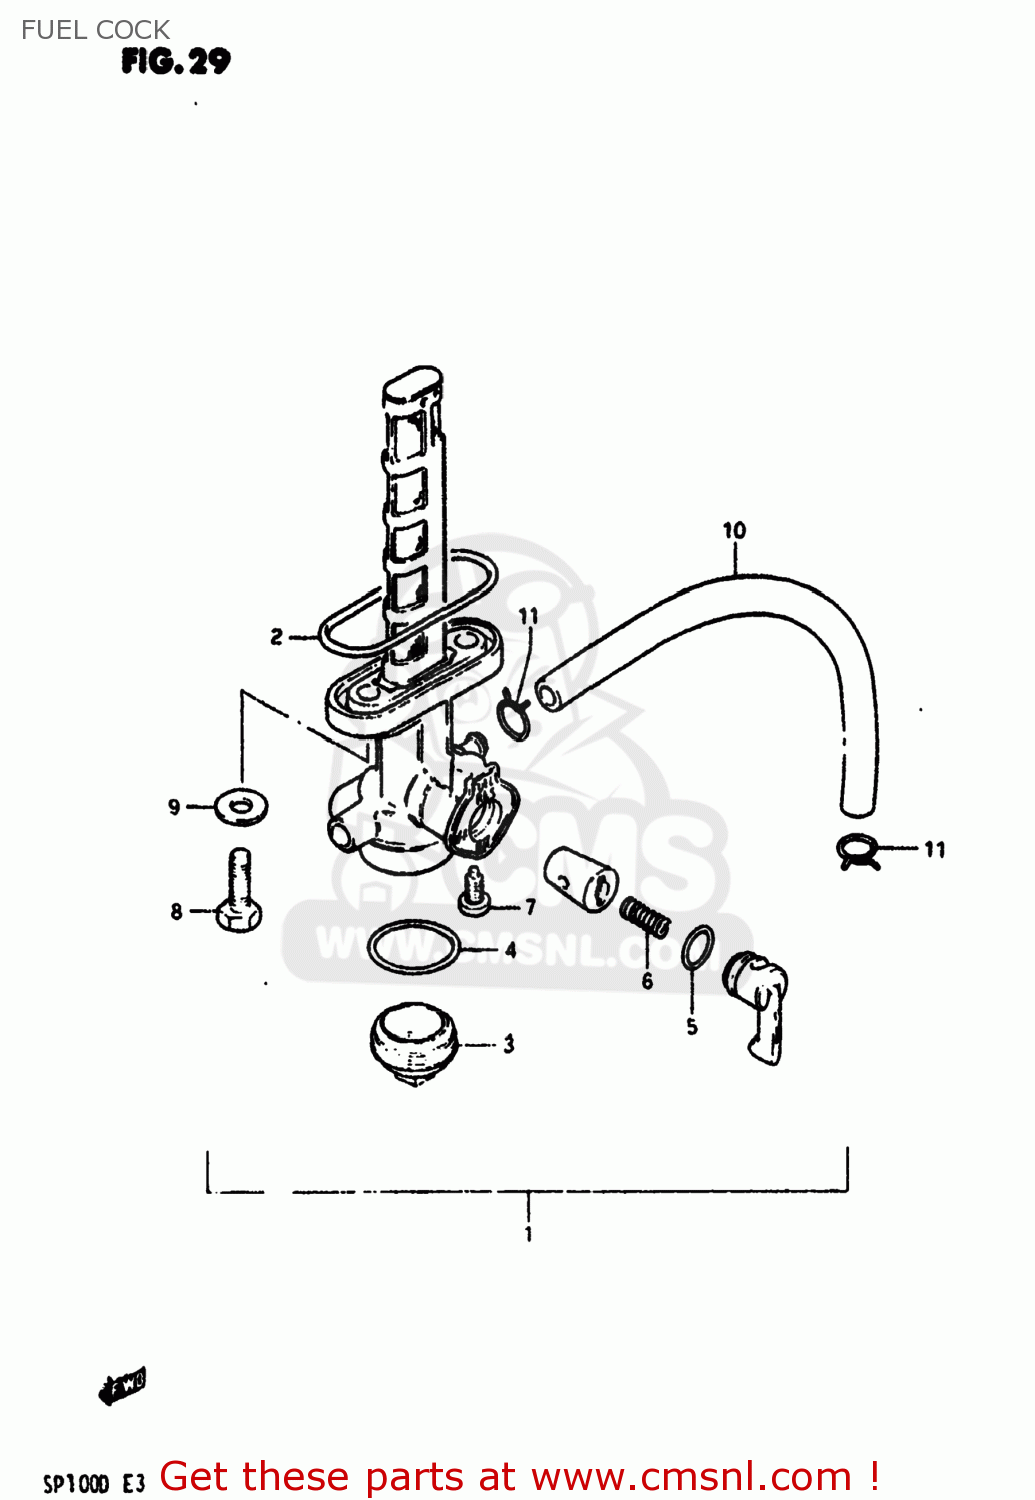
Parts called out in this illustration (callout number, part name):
1	COCK ASSEMBLY,FUEL
2	O RING,FUEL COCK
3	CUP,STRAINER
4	GASKET,FILTER (NAS)
5	O-RING
6	SPRING
7	SCREW
8	BOLT(6X20)
9	GASKET
10	HOSE
11	CLIP
